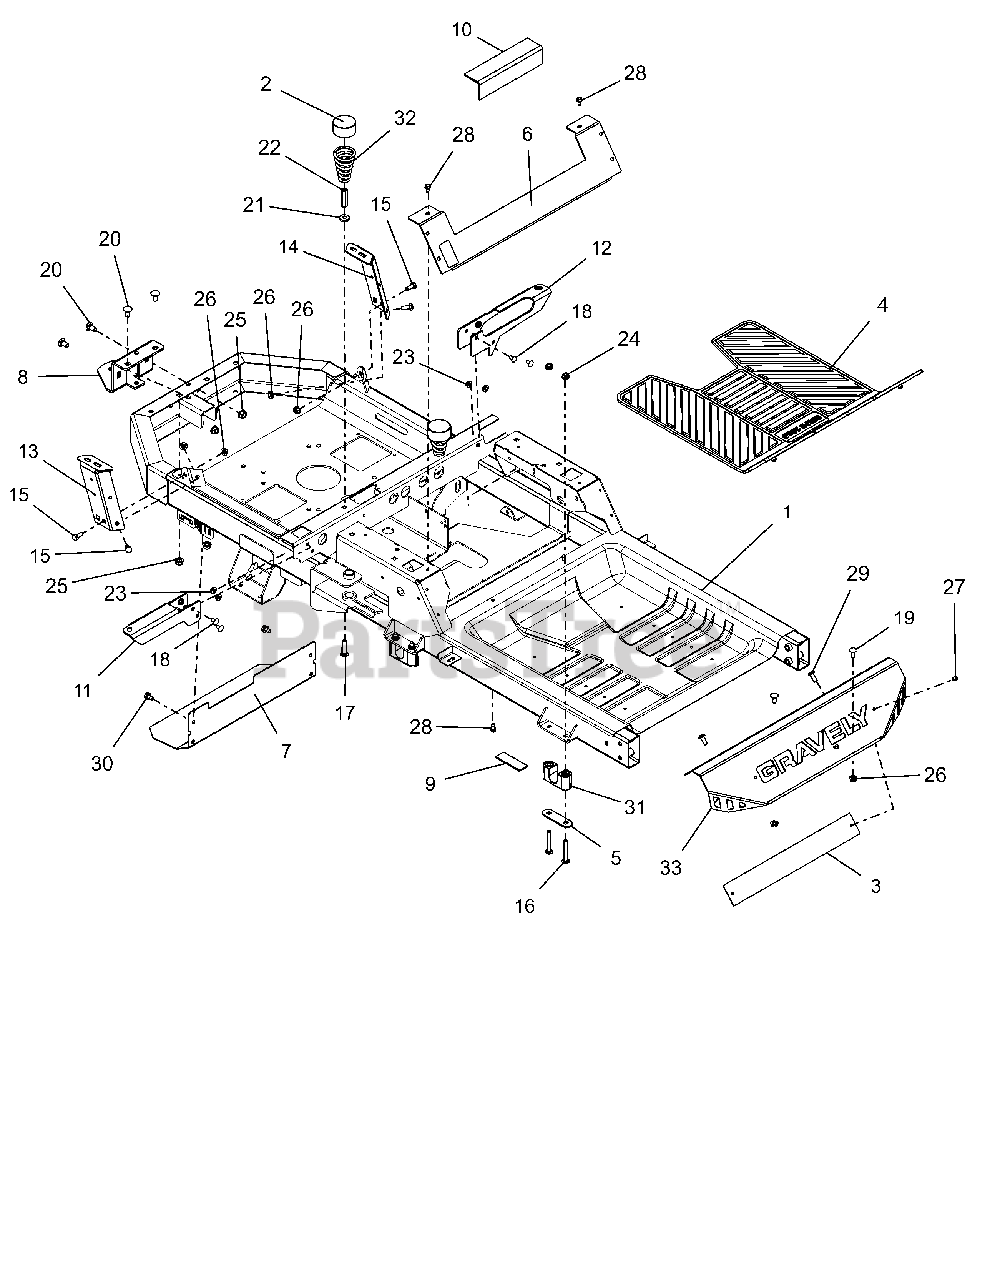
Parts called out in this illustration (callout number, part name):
1	KIT, ZT-X/XL FRAME SERVICE
3	PLATE, BACK FOOT-REST XL
4	FLOOR MAT, RUBBER - GRAVELY
5	PLATE, BEARING SUPPORT
6	PLATE, SEAT KICK
7	HEAT, SHIELD
8	BRKT, HITCH TONGUE
9	PAD,RBR 1.0"X3.0" W/ADHESIVE
10	PAD, RUBBER-TANK
11	BRKT,CROSS EXTENSION - LH
12	BRKT,CROSS EXTENSTION - RH
13	MOUNT,FENDER-RH EXTENSION
14	MOUNT,FENDER-LH EXTENSION
15	@BLT-HEX .31-18X.75 GR5 YWZC
16	BLT-RDHDSQSHNK .31-18X2.25 YWZ
17	@BLT-RDHDSQNK .31-18X1.50 G5YZ
18	BLT-RDHDSQSHNK.25-20X.50 YWZC
19	@BLT-RDHDSQNK .31-18X.75 G5YZ
20	@BLT-RDHDSQNK .38-16X.75 G5YZ
21	WSHR-FL-STL .328X.87X.179 YWZC
22	NUT, COUPLING 5/16-18 X 1 3/4
23	NUT-LK-CTR-FLG .25-20 YWZC
24	@NUT-LK-CTR-FLG .31-18 YZ GR F
25	@NUT-LK-TOP-FLG .38-16 YWZC
26	@NUT-LK-TOP-FLG .31-18 YWZC
27	RIVET, .1875 AL/AL .126-.250
28	SCR-TAP .25-20X.50 HWH TR YWZ
29	SCR-RDHDSKTAP .31-18 X .75
30	@SCR-TAP .31-18X.50 HWH TR YWZ
31	BSHG, DECK LIFT PIVOT
32	SPRING, SEAT
33	KIT, FOOTPLATE W/DECAL-ZTX
